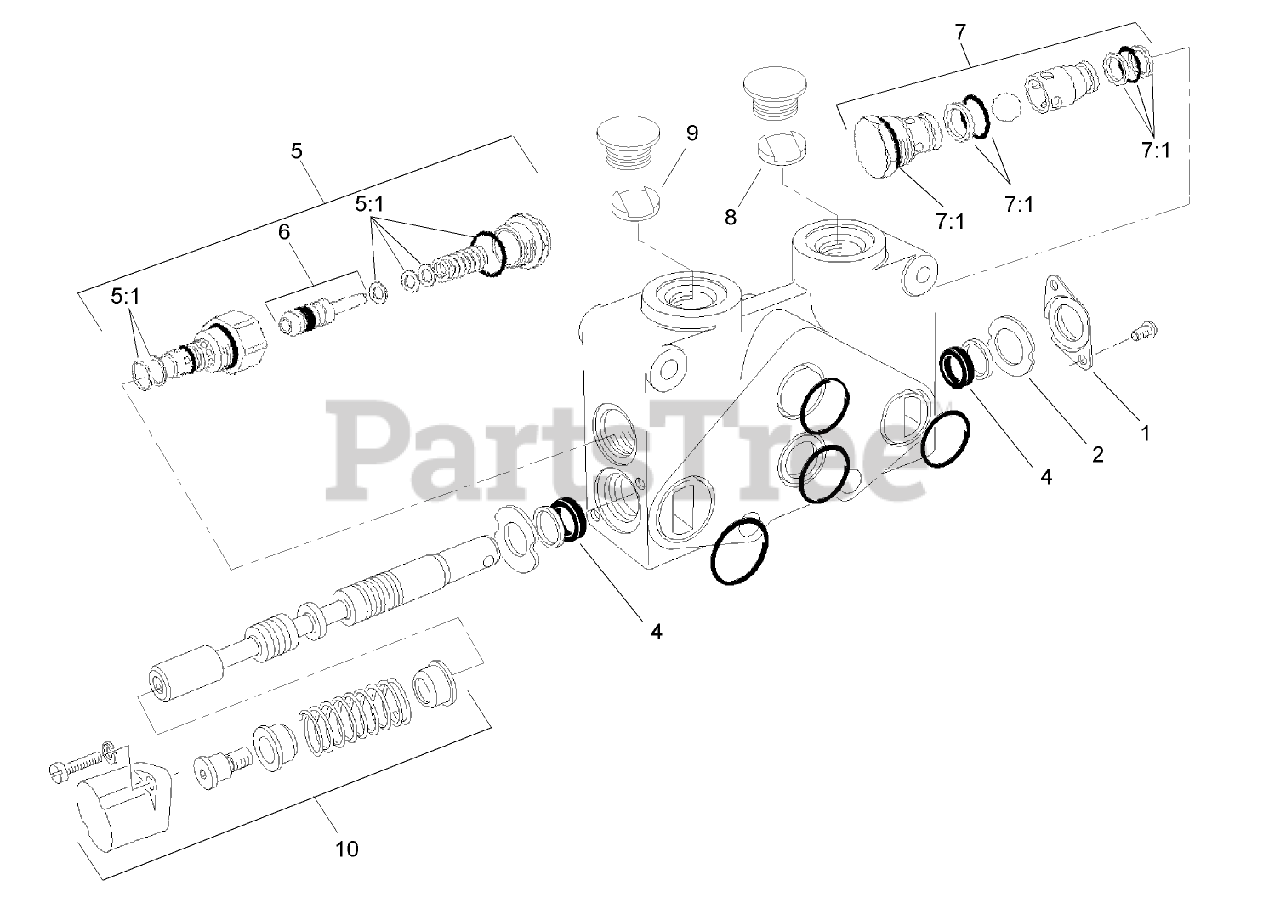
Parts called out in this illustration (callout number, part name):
1	PLATE-RETAINER, SEAL
2	PLATE-RETAINER, SEAL
4	SPOOL SEAL KIT
5	CARTRIDGE-RELIEF
5:1	CARTRIDGE SEAL KIT
6	POPPET RELIEF ASM
7	CARTRIDGE-ANTICAVITATION
7:1	CARTRIDGE SEAL KIT
8	RESTRICTOR (.062IN)
9	RESTRICTOR (.100IN)
10	SPOOL POSITIONER KIT
